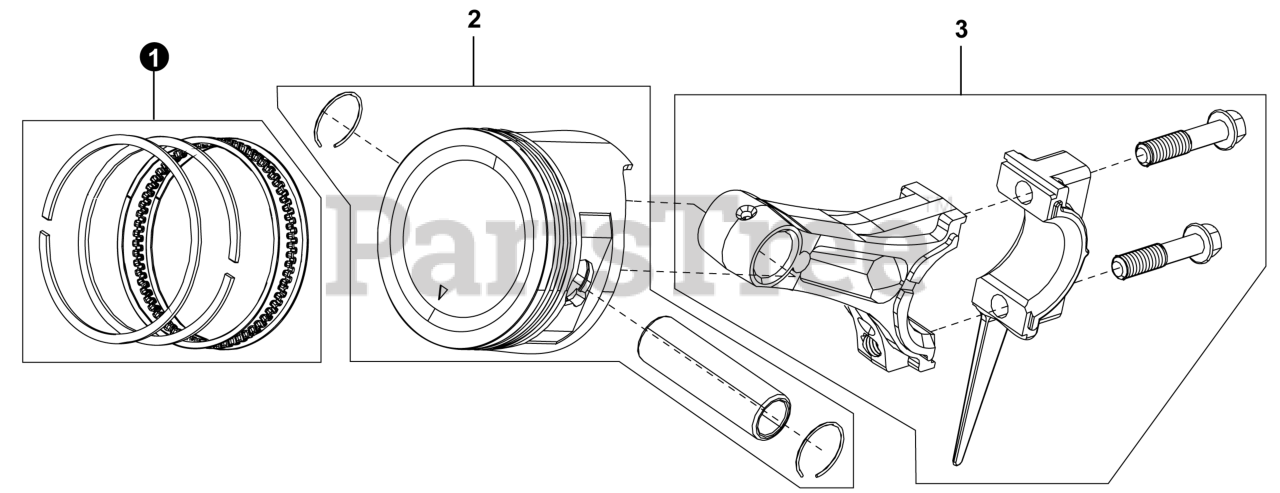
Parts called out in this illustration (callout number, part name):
1	SET, PISTON RING
2	KIT, PISTON
3	ASSY., CONNECTING ROD
